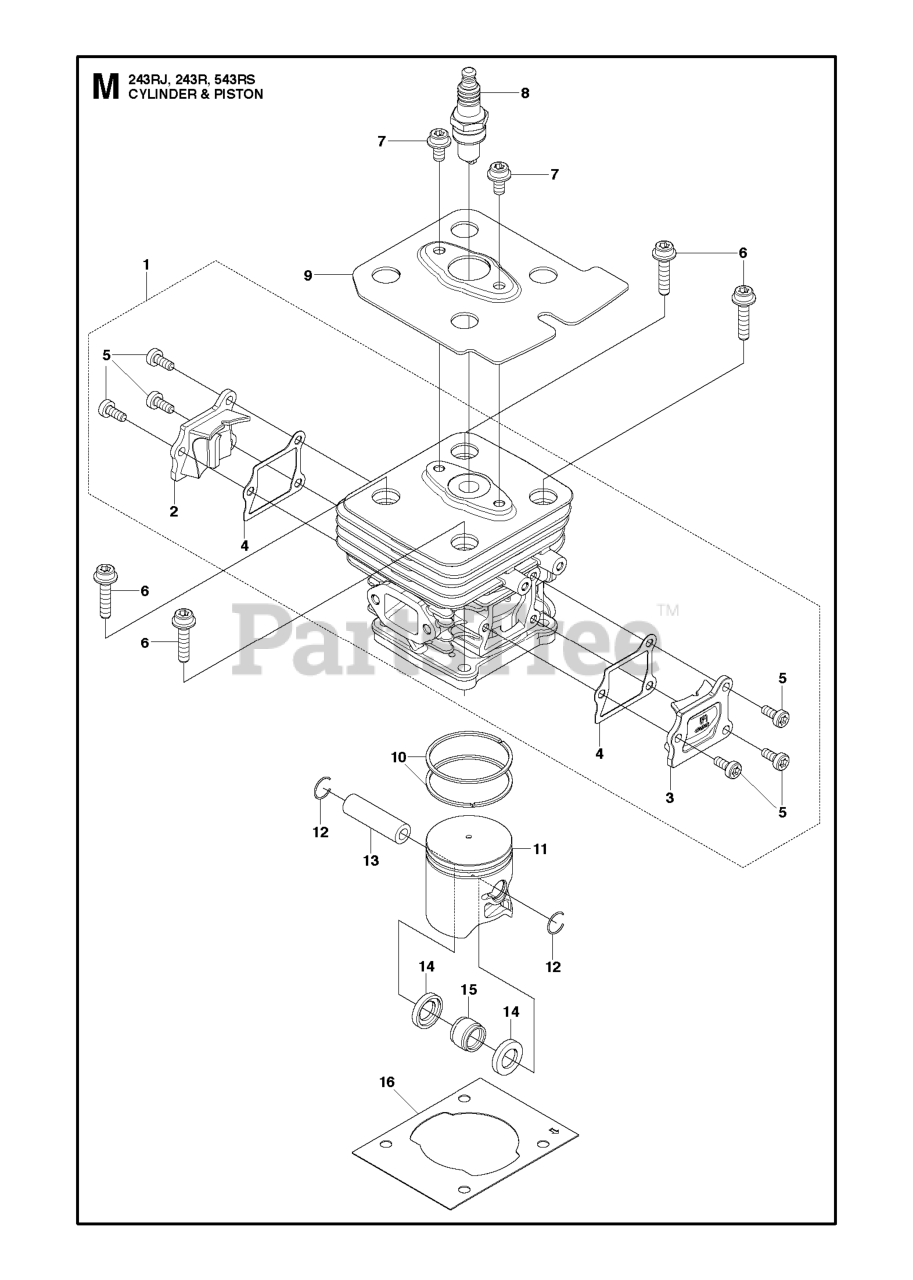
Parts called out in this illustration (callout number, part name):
1	CYLINDER-COMP 848GG01211
1	CYLINDER ASSY
2	COVER TRS STARTER SIDE
3	COVER,TRF FLYWHEEL SIDE
5	SCREW
6	BOLT TORX
7	BOLT (RPLS T495051010-11)
8	SPARK PLUG NGK CMR7H
10	PISTON RING
11	PISTON
11	PISTON 848GG041A0
14	THRUST WASHER
15	BEARING
